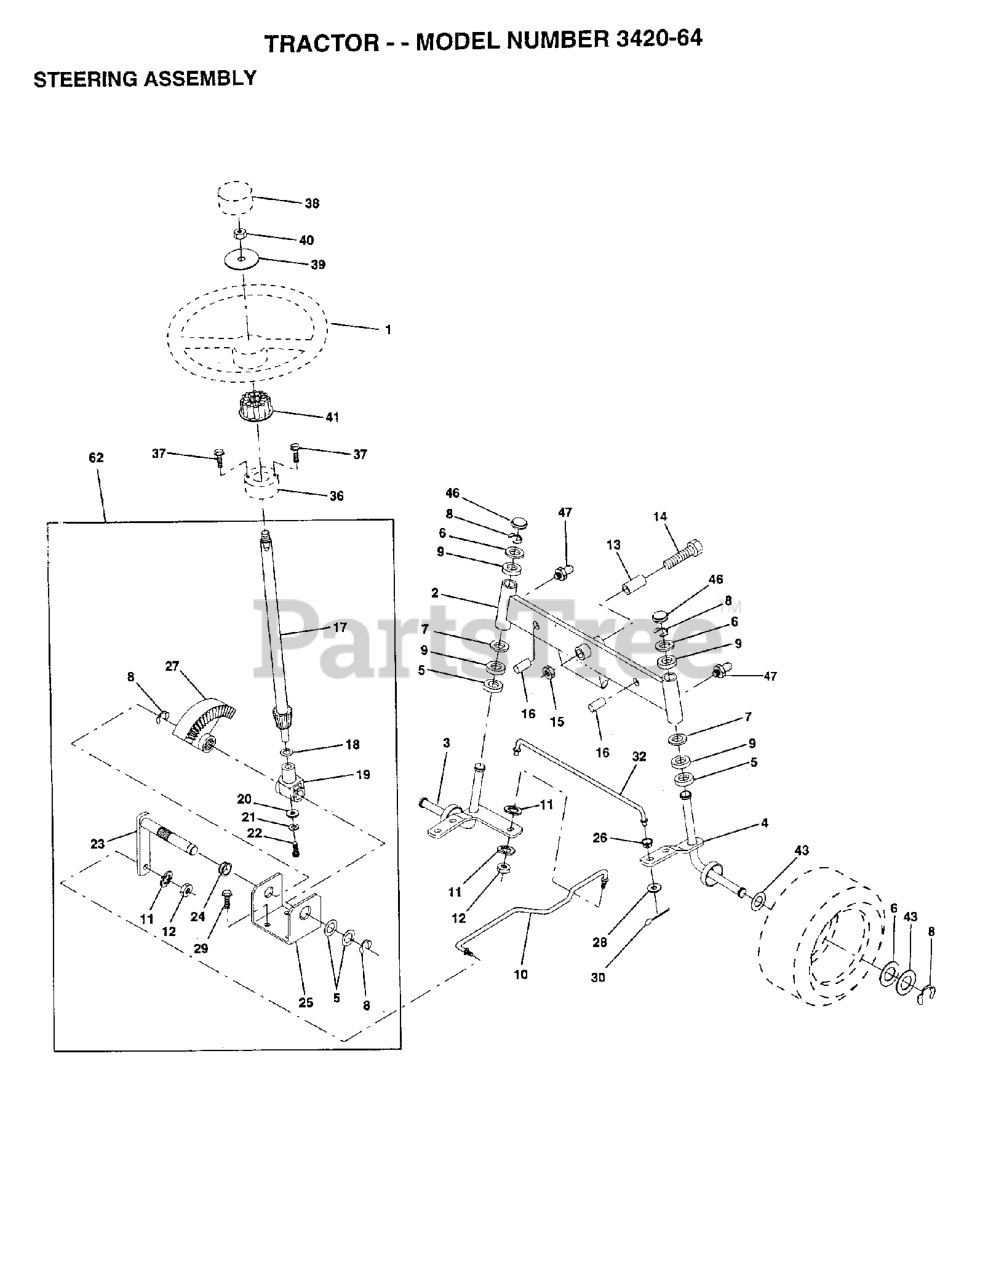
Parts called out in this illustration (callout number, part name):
1	Steering Wheel
2	AXLE ASSY
5	WASHER THRUST
8	RING CLIP
9	BEARING.STEERING.COLUMN
10	DRAG LINK
11	WASHER, LOCK 3/8
12	NUT
14	BOLT.HEX.5/8-11
15	LOCK NUT
18	THRUST WASHER
19	SHAFT,SUPPORT
20	WASHER
21	LOCKWASHER
22	SCREW
23	SHAFT,PITMAN
24	NYLINER T (7283A)
25	BRKT,STEERING
26	BUSHING STEERING
27	GEAR.SECTOR
28	WASHER
30	COTTER PIN
36	BUSHING STRG 3/4
37	SCREW.TT.#10-32X.5.3/8.FLANGE
38	INSERT STR WHL
40	NUT.HEX.1/2-20
46	CAP.SPINDLE.BLACK
47	ZERK.GREASE.TAPERED
62	STEERING KIT
